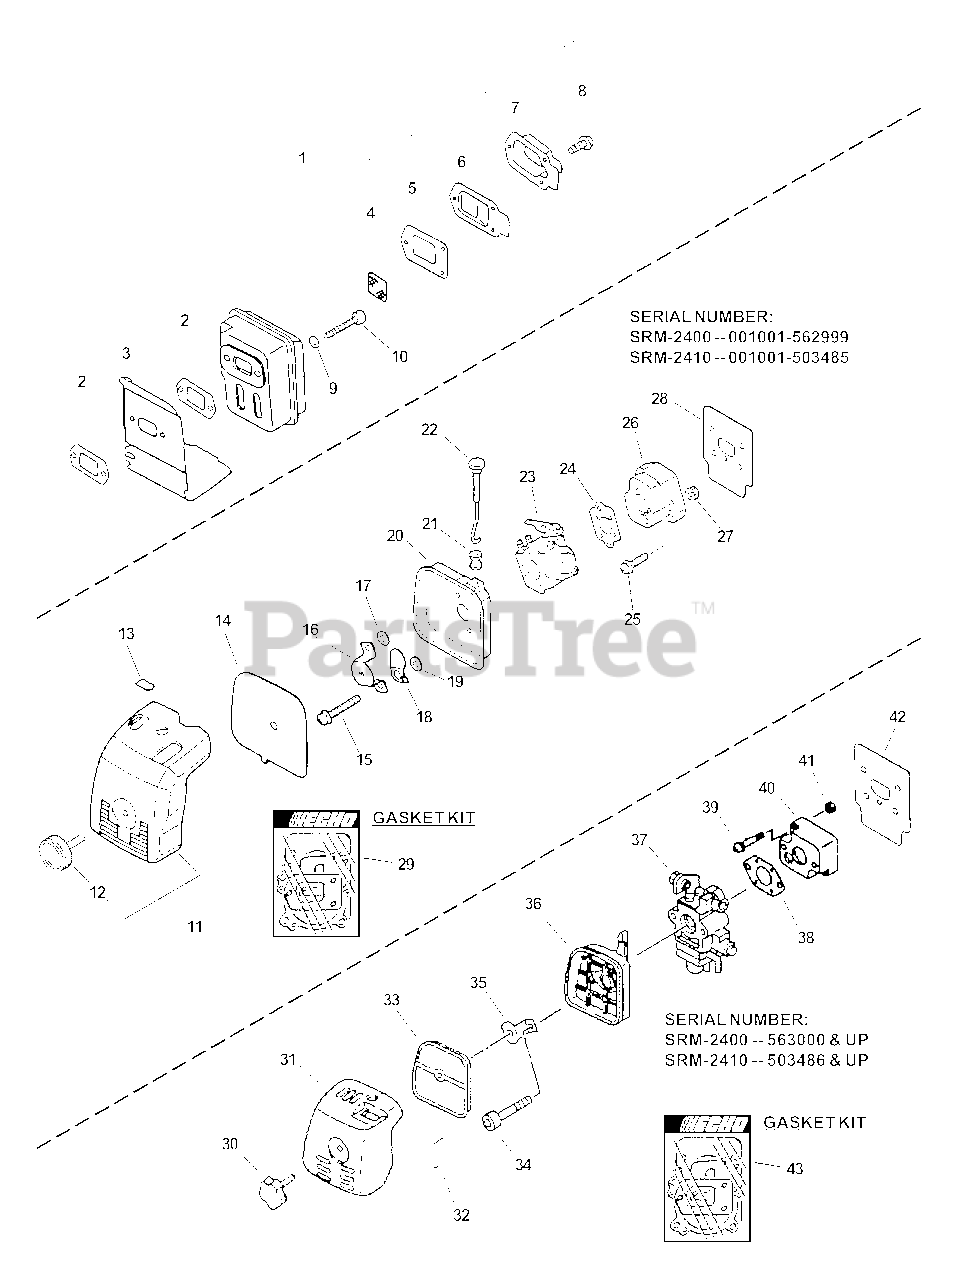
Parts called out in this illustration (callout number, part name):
1	MUFFLER ASSY
2	GASKET, EXHAUST
3	SHIELD, EXHAUST
4	SCREEN, SPARK ARRESTOR
5	GASKET, EXHAUST
6	GASKET, EXHAUST - INNER
7	GUIDE, EXHAUST - OUTER
8	SCREW - 4X10
9	WASHER - 5
10	SCREW - 5X55
11	AIR FILTER COVER ASSY
12	THUMBSCREW
13	LABEL - CHOKE
14	FILTER, AIR - HEAVY DUTY
15	SCREW - 5X57
16	PLATE, PREVENT
17	WASHER - 5
18	SHUTTER, CHOKE
19	WASHER - 5
20	CASE, AIR FILTER
21	GROMMET
22	ROD, CHOKE
23	CARBURETOR WT-424A
24	GASKET, INTAKE
25	SCREW - 5X20
26	INSULATOR, INTAKE
27	NUT - 5
28	SHIELD, INTAKE
29	GASKET KIT
30	THUMBSCREW
31	COVER, AIR FILTER
32	LABEL - CHOKE
33	FILTER, AIR - HEAVY DUTY
34	SCREW - 5X65
35	PLATE, PREVENT
36	CASE, AIR FILTER
37	CARBURETOR WYJ-220
38	GASKET, INTAKE
39	SCREW - 5X20
40	INSULATOR, INTAKE
41	NUT - 5
42	SHIELD, INTAKE
43	GASKET KIT
